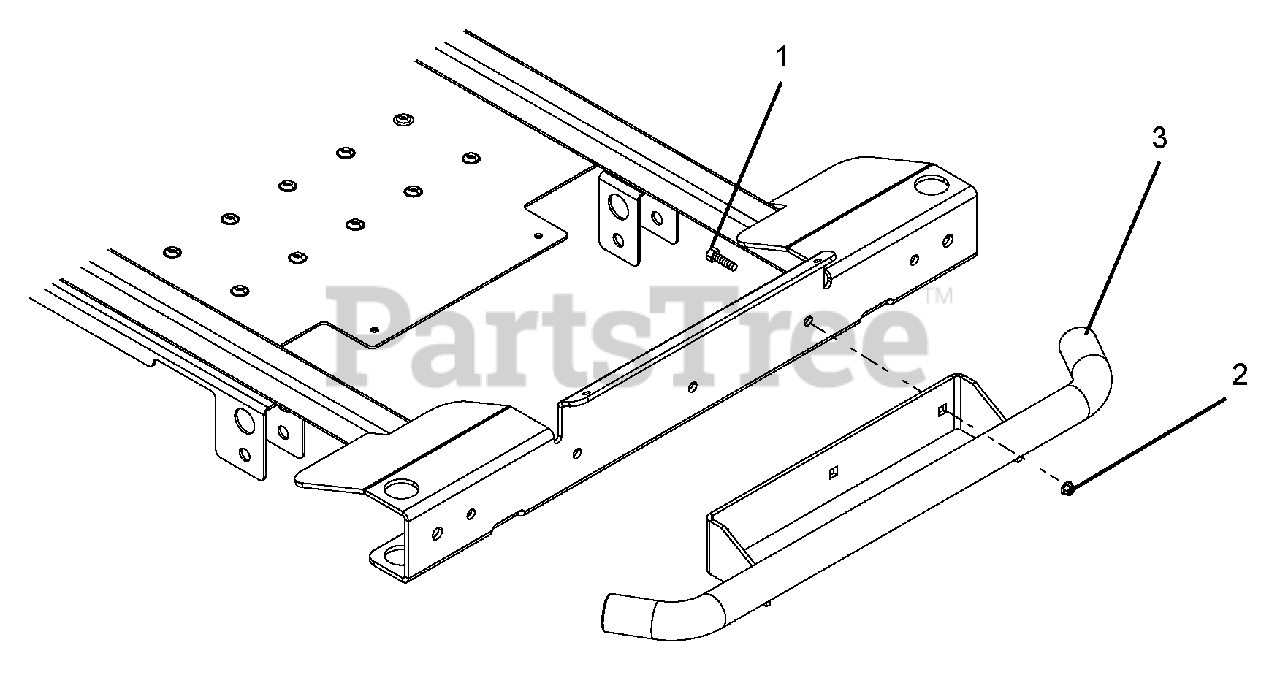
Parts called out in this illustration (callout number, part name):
1	Bolt-Hex .38-16 x 1.00 Grade 5
2	Nut, Flange Nyloc .38-16
3	Front Bumper
